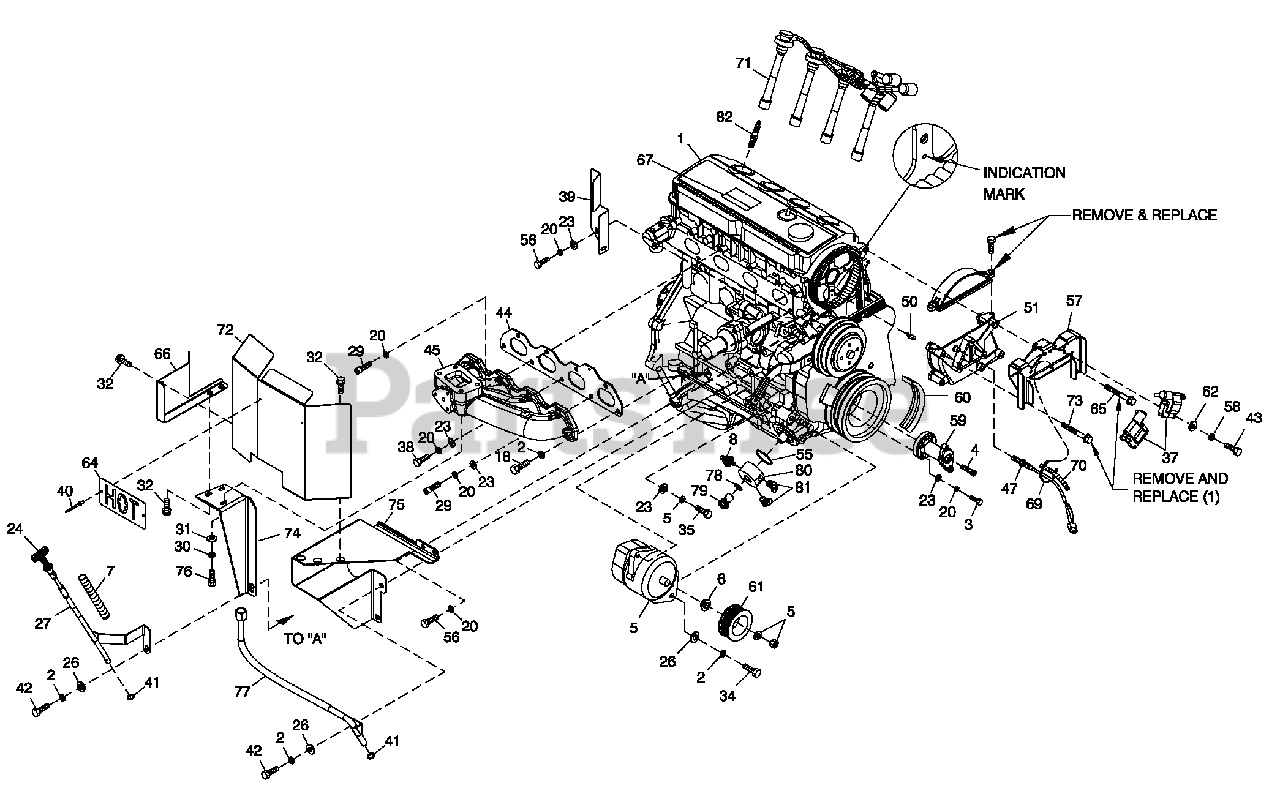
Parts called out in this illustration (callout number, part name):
1	ENGINE 2.4LG2
2	WASHER LOCK M10
3	SCREW HHC M8-1.25X35 G88
4	SCREW SHCM14-1.5X 35 G 10.9
5	ALTERNATORDC W/O U T PULLEY
6	SPACERDC ALTERNATOR PULLEY
7	CONDUIT THERMAL FLEX 13MM ID
8	SWITCH OIL PRESSURE 10 PSI2 POL (R-PANEL)
18	SCREW HHC M10-1.25 X30G8.8
20	WASHERLOCK M8-5/16
23	WASHER FLAT 5/16-M8ZINC
24	ASSY DIPSTICKW/TEXT GTH-530
26	WASHER FLAT 3/8-M10ZINC
27	ASSY DIPSTICKTUBE2.4 G2
29	SCREWSHC M8-1.25X 25 G129
30	WASHER LOCKM6-1/4
31	WASHER FLAT 1/4-M6ZINC
32	SCREW HHTTM6-1.0X 12 ZINC
34	SCREW HHC M10-1.5X 60 G8.8
35	SCREW HHC M8-1.25 X 25 G10.9
37	COIL-2.4LG2 IGNITION
38	SCREW HHC M8-1.25 X 30 C8.8
39	SHIELD HEAT IGNITION COIL 2.4L
40	RIVET POP .125X 0.337STEEL
41	O-RINGSZE 9.0MMX 2.0MM NTR
42	SCREW HHC M10-1.25 X 20 C8.8
43	SCREW HHM #10-32X1-1/4
44	GASKET EXHAUST MANIFOLD
45	MANIFOLD EXH 60K G2 T URBO (MA)
47	ASSYMAGPICK UP(3/8-24MALE)
50	CAMSENSORPINASSY
51	COVER CAM GEAR G2 REWORKED
55	O-RING 2.5'X 2.75"X 1/8" VITON
56	SCREW HHC M8-1.25X 16 C8.8
57	BRACKET ASM-24L COIL G2
58	WASHER LOCK#10
59	ADAPTER2.4L CRANKSHAFT MACH
60	POLYV-BELT G2 (3600 RPM)
61	PULLEY DC ALTERNATOR (3600 RPM)
62	WASHER FLAT #10 ZINC
64	PLATE "HOT"
65	SCREW HHC M8-1.25 X 70 G8.8
66	SHIELD INNER HEAT 2.4L TURBO
67	DECAL EM ISSION CT RL INFO 2.4L
69	TIEWRAP UL7.4"X.19" BLK
70	COND UTFLEX.25"ID
71	SPARKPLUG WIRE SET 2.4LG2 IG
72	HEAT SHIELDTURBO 2.4L
73	SCREW HHC M8-1.25 X 65 C8.8
74	BRACKET EXH MANIFO LD 2.4 T URBO
75	BRACKET HEAT SHIELD 2.4L
77	T UBE T URBO OIL RET URN G22.4L
78	O-RING 1 "X 1.25'X 1/8" VITON
79	N UT OIL FILTER ADAPTOR 2.4L G2
80	ADAPTOR OIL FILTER2.4L G2
81	ADAPTOR 45D JIC37 1/2NPTX 3/4
82	PLUG SPARK
